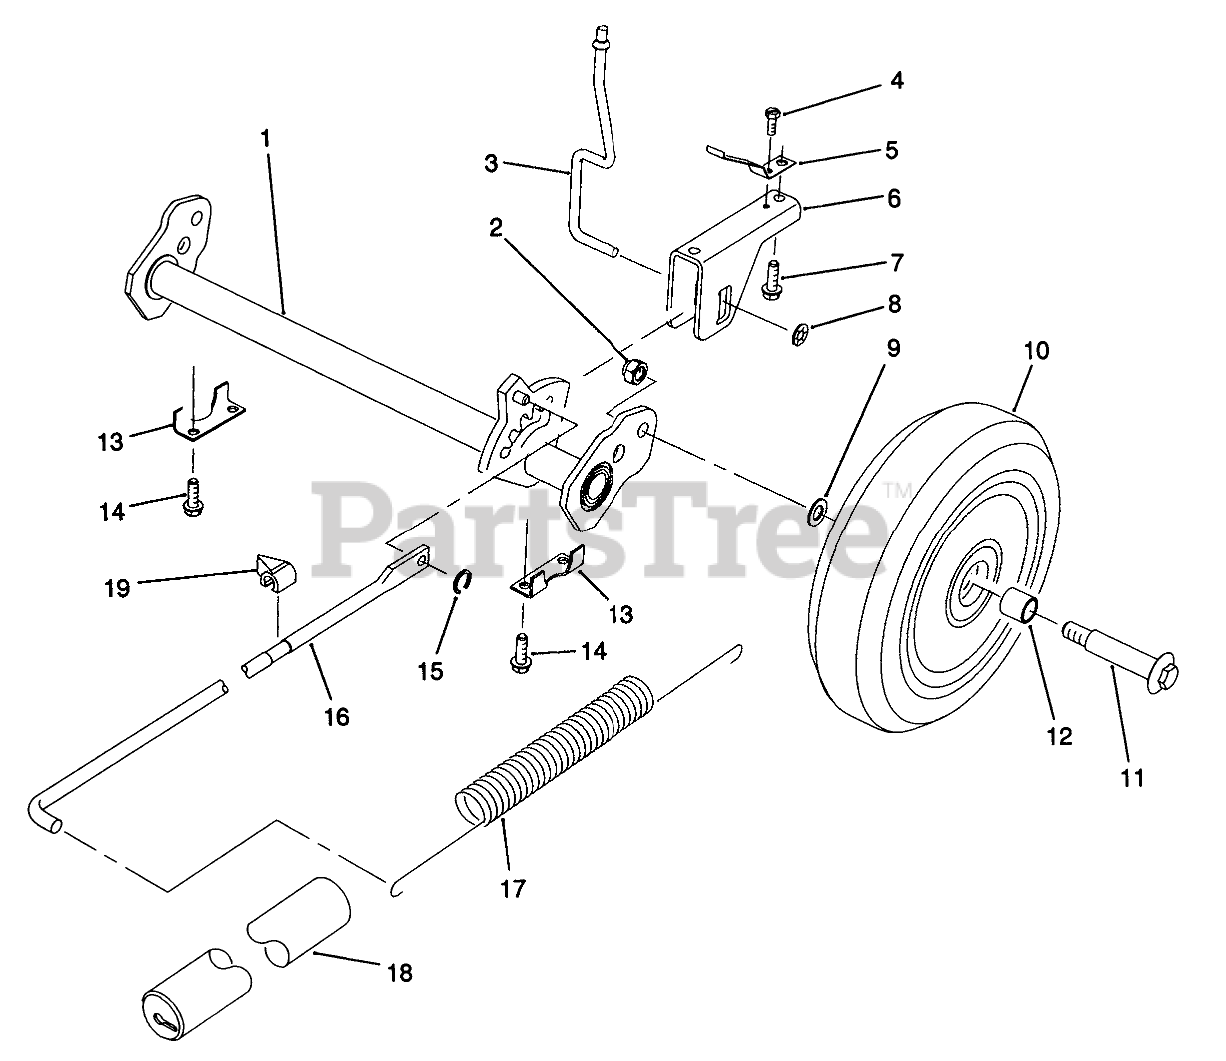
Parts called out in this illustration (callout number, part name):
1	PIVOT ARM REAR WA
2	NUT-HEX
3	TRIGGER ROD
4	SCREW 8 - 32 X 250
5	SPRING - TRIGGER RET
6	SADDLE - HOC
7	SCREW
8	PUSHNUT
9	WASHER
10	Wheel & Tire Assembly (Incl. Ref. #12)
11	BOLT-WHEEL
12	BUSHING
13	REAR SECURING PLATE
14	SCREW-HWHTF
15	GRIP RING
16	LINK ROD
17	SPRING-COUNTERBALANCE
18	COVER-SPRING
19	INDICATOR-HEIGHT OF CUT
